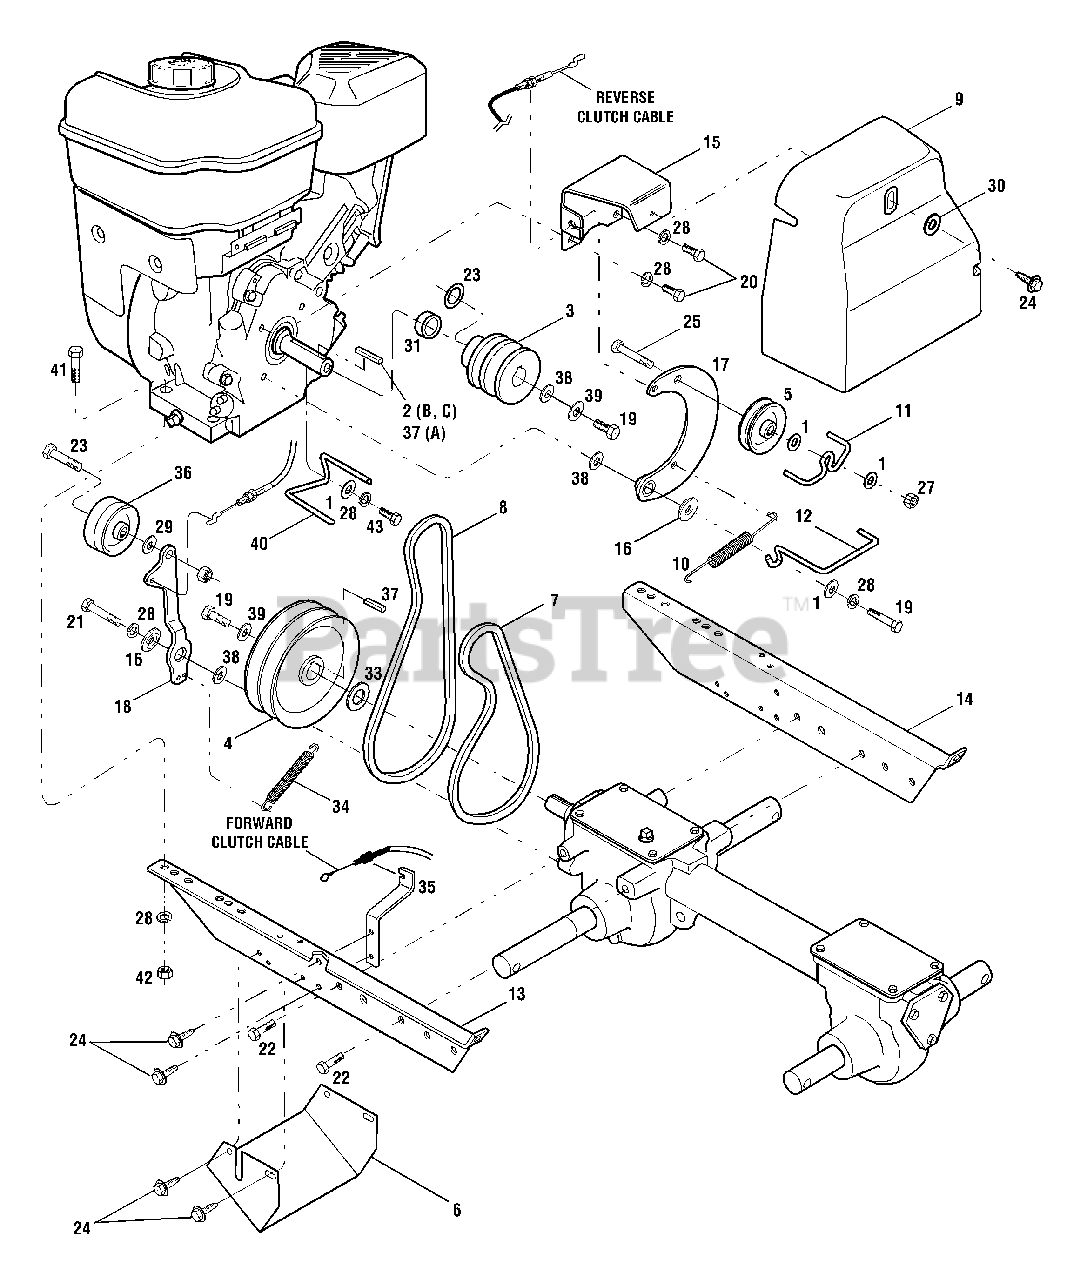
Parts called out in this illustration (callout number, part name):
1	Flat Washer, 5/16
2	Key, 3/16" x 1-1/2"
3	Pulley, Engine Drive
4	Transmission Pulley
5	Pulley, Reverse Idler
6	Guard, Belts/Pulleys
7	Forward Drive Belt
8	Reverse Drive Belt
9	Belt Cover
10	Reverse Return Spring
11	Belt Guide
12	Forward Belt Guide
13	Engine Bracket, Left
14	Engine Bracket, Right
15	Bracket, Belt Cover
16	Shoulder Washer
17	Reverse Idler Arm
18	Forward Idler Lever
19	Hex Hd. Screw, 5/16-24 x 1
20	Hex Hd. Screw, 5/16-24 x 5/8
21	Hex Hd. Screw, 5/16-18 x 1
22	Hex Hd. Screw, 5/16-18 x 5/8
23	Hex Hd. Screw, 3/8-16 x 1-1/2
24	Screw, Self-Tapping, 1/4-20 x 1/2
25	Hex Hd. Screw, 5/16-18 x 2
27	Lock Nut, 5/16-18
28	Lock Washer, 5/16
29	Flat Washer, 3/8
30	Flat Washer
31	Spacer
33	Support Washer
34	Forward Return Spring
35	Bracket, Cable Mounting
36	Forward Idler Pulley
37	Key, 3/16" x 1"
38	Flat Washer
39	Belleville Washer
40	Forward Belt Guide
41	Hex Hd. Screw, 5/16-18 x 1-1/2
42	Hex Nut, 5/16-18
43	Hex Hd. Screw, 5/16-24 x 3/4
